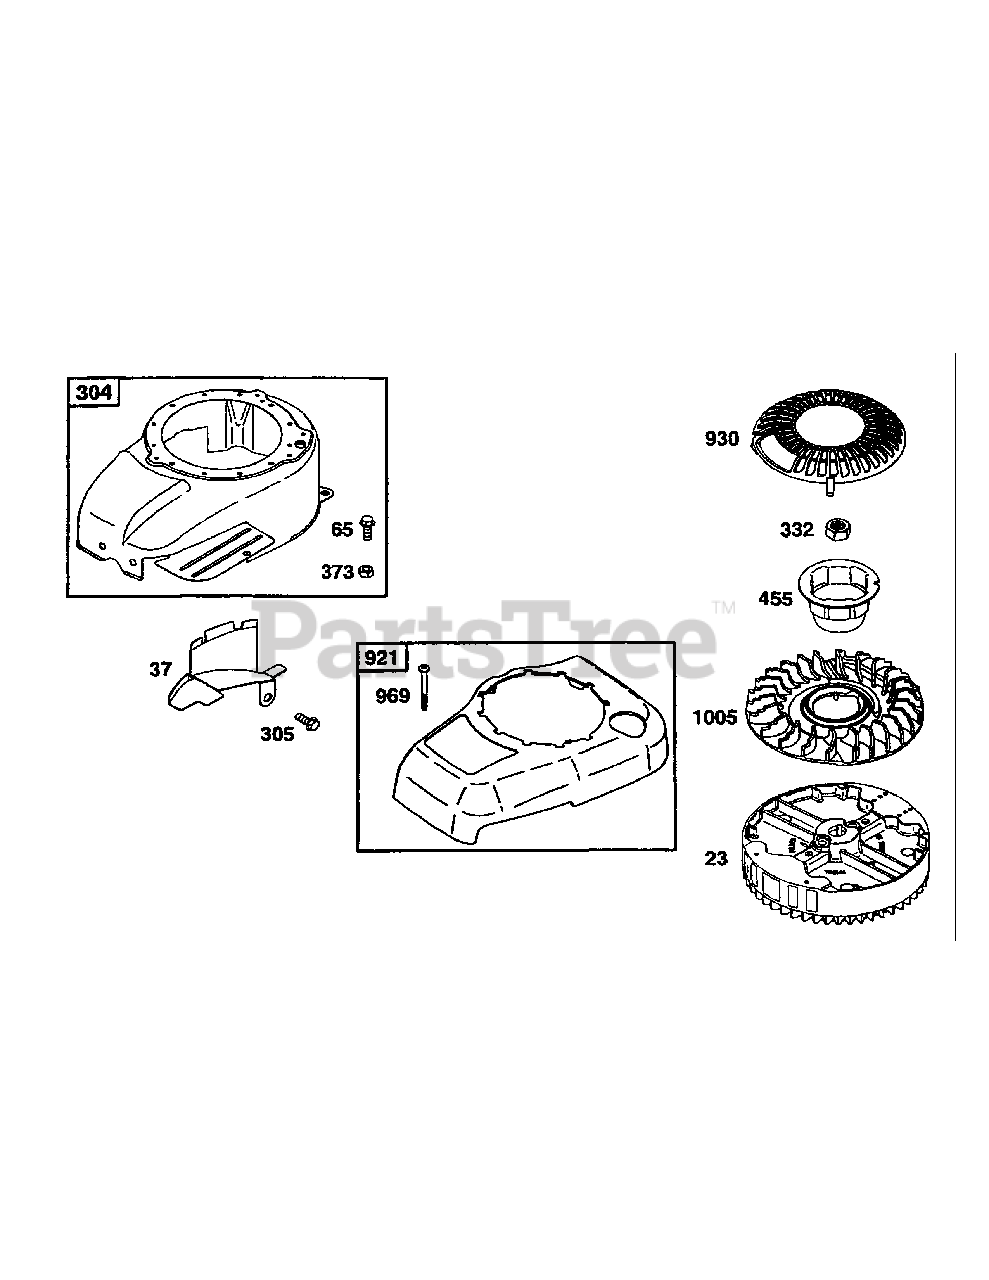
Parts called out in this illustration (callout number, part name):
23	Flywheel
37	Flywheel Guard
65	Hex Screw
304	Blower Housing
305	Hex Screw
332	Flywheel Nut
373	Hex Nut
455	Flywheel Cup
921	Blower Housing Cover
930	Rewind Guard
969	Blower Housing Cover Screw
1005	Flywheel Fan
